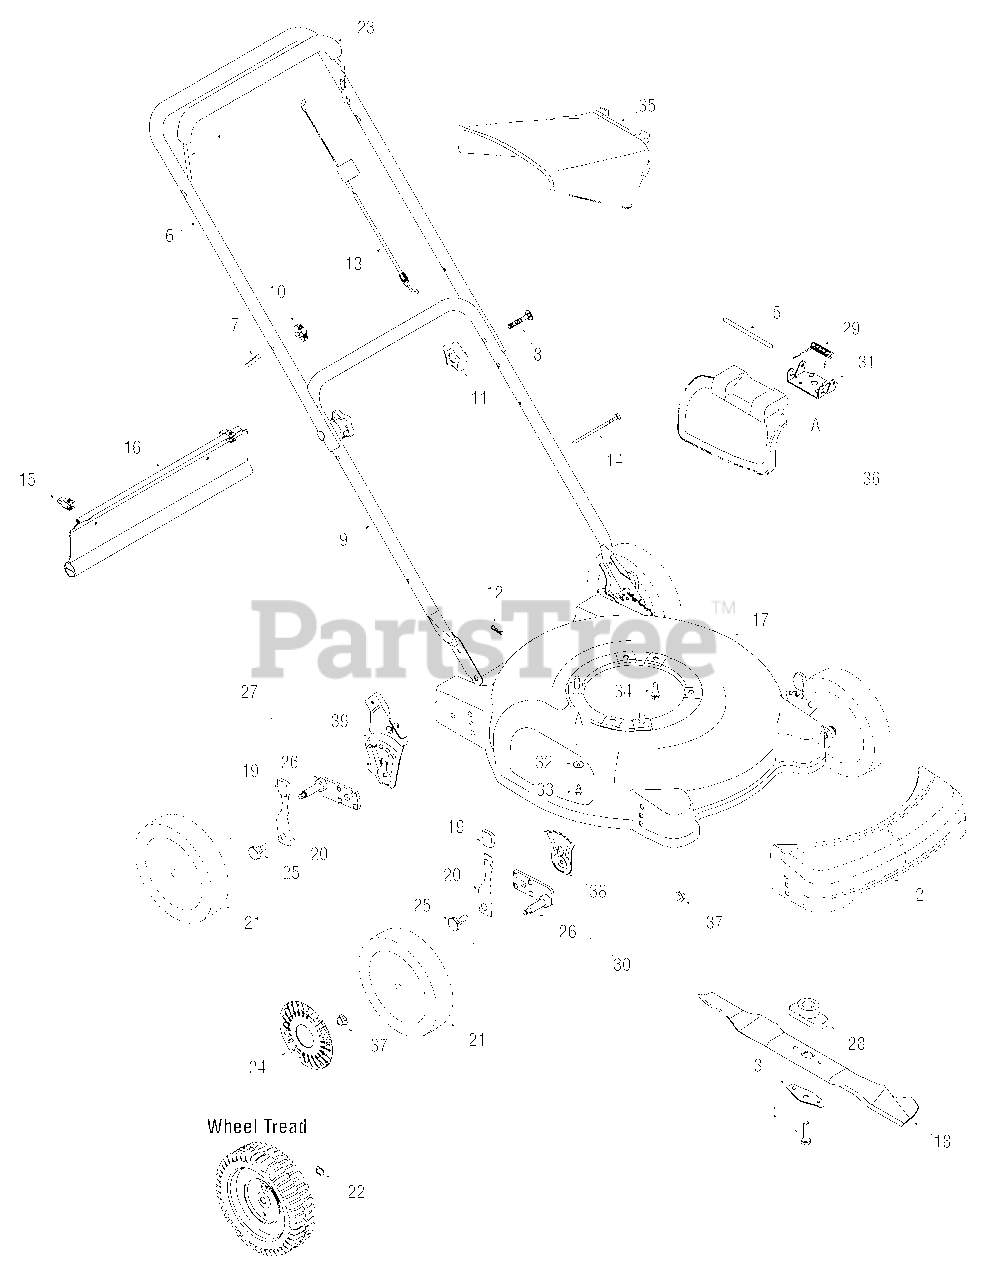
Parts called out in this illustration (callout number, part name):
2	Front Cover
3	Blade Bell Support
5	Hinge Pin
7	Rope Guide
8	Carriage Bolt
11	Star Knob
12	Hairpin Clip
13	Control Cable 37.25"
14	Cable Tie
15	Hinge Clip
16	Trail Shield
19	Height Adjustment Knob
20	Spring Lever
21	Wheel Assembly 8 x 2.125
22	Wave Washer
23	Deluxe Bail Cover
24	Hubcap: Radial Spoke Gray
25	Shoulder Bolt
26	Pivot Arm Assembly - use position RH Front
26	Pivot Arm Assembly - use position LH Rear
26	Pivot Arm Assembly - use position LH Front
26	Pivot Arm Assembly - use position RH Rear
27	Handle Bracket Assembly RH
27	Handle Bracket Assembly LH
28	Blade Adapter
28	Blade Adapter Kit (for service)
29	Torsion Spring
30	Height Adjust. Assembly LH
30	Height Adjust. Assembly RH
32	Bell Washer
33	Hex Washer Hd. TT Screw
34	TT Sems Screw
35	Chute Deflector
36	Mulching Plug Assembly
37	Hex Lock Nut
38	Height Adjustment Plate
